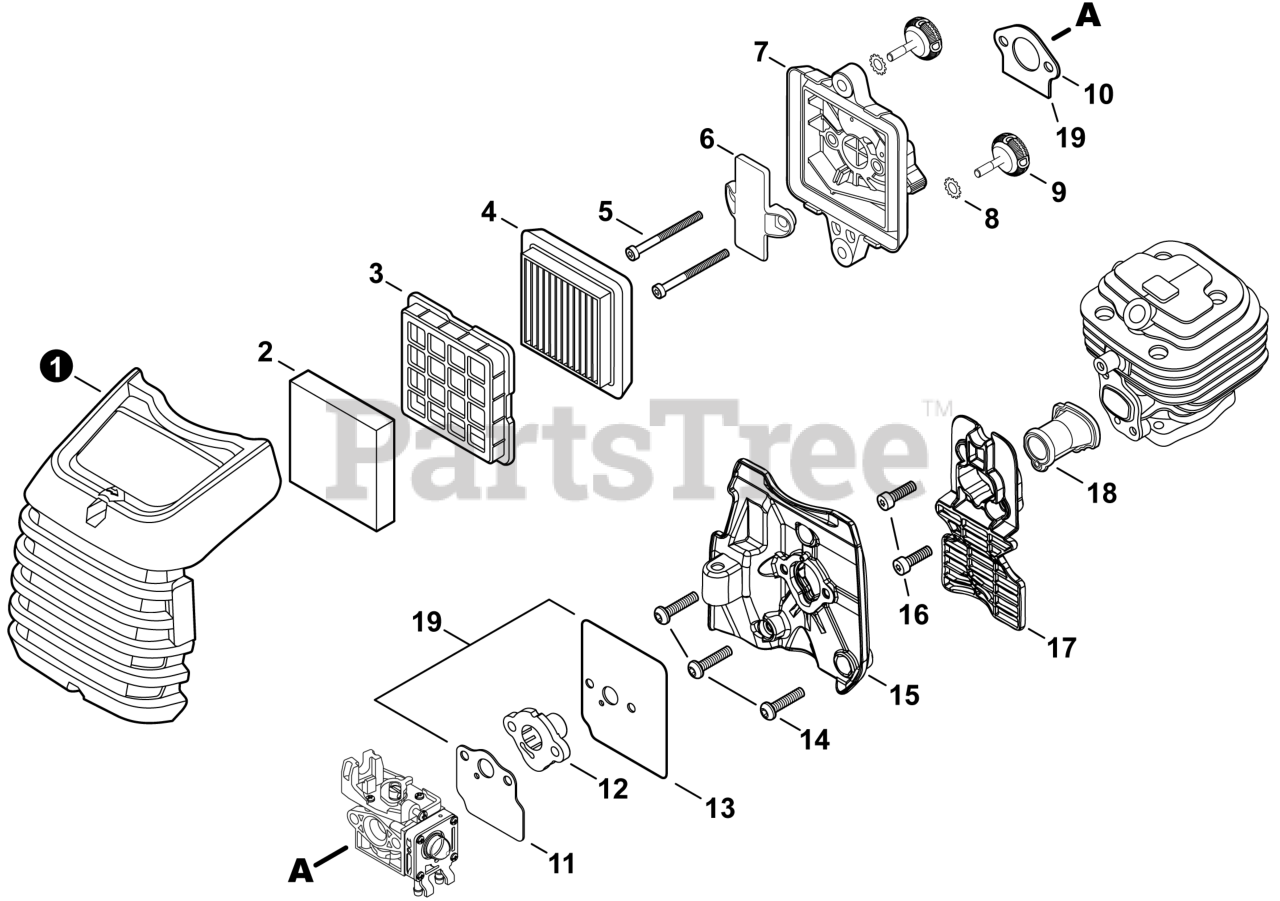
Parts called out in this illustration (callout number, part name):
1	COVER, AIR FILTER
2	PRE-FILTER, FOAM
3	RETAINER, PRE-FILTER
4	FILTER, AIR
5	BOLT, TORX 5x60
6	PLATE, PREVENT
7	CASE, AIR FILTER
8	WASHER, LOCK
9	THUMBSCREW
10	GASKET, INTAKE
11	GASKET, BOOT
12	BOOT, INTAKE
13	GASKET, INSULATOR PLATE
14	BOLT, TORX 5x16
15	PLATE, INSULATOR
16	BOLT, TORX 5x16
17	HOLDER, BELLOWS
18	BELLOWS, INTAKE
19	GASKET KIT
